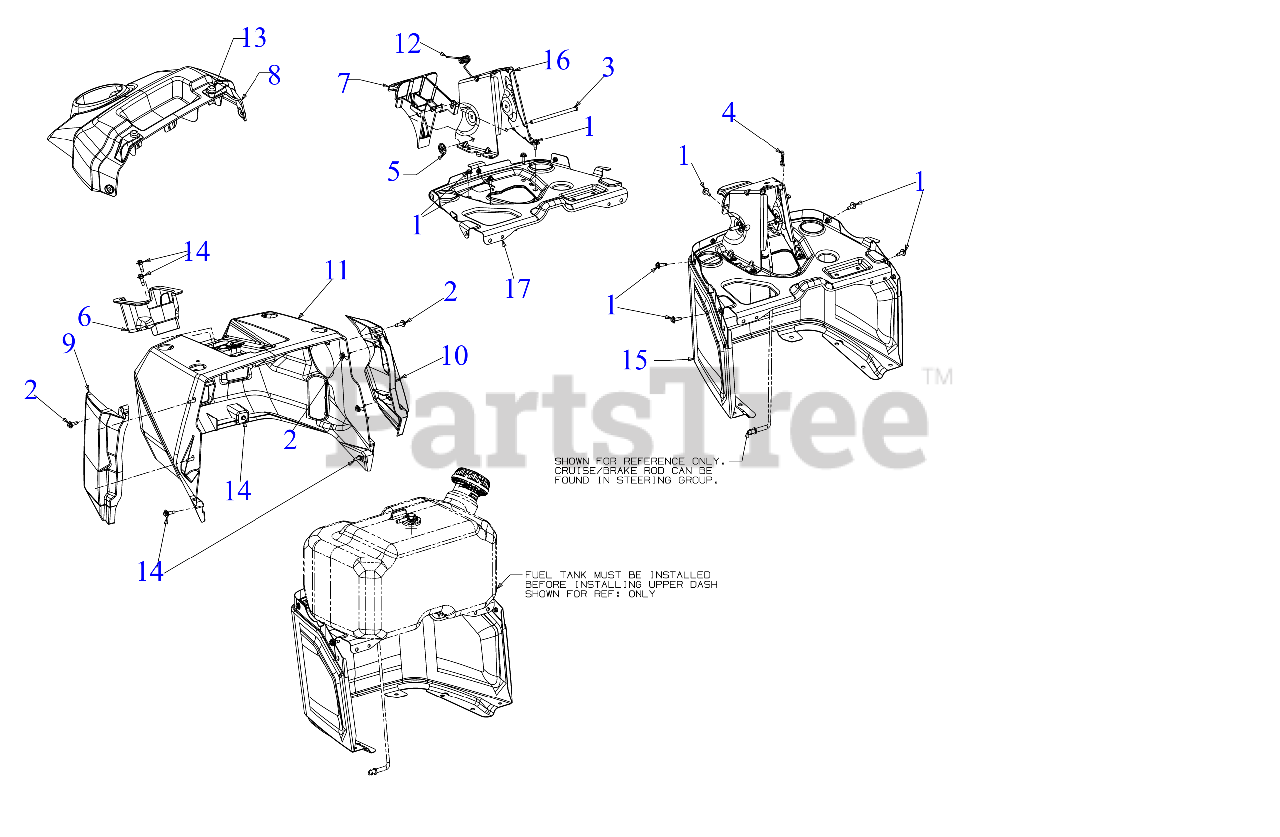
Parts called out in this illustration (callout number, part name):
1	SCREW M6-1 x .625
2	SCREW 1/4-10 x .750
3	HINGE PIN .25 x 4.50
4	BOW TIE COTTER PIN 1/4-5/16
5	PUSH NUT
6	STEERING SHAFT BEARING
7	CRUISE/BRAKE DASH LEVER
8	UPPER DASH CAP (CRAFTSMAN)
9	DASH SIDE CAP (RH)
10	DASH SIDE CAP (LH)
11	UPPER DASH
12	TORSION SPRING .330 ID
13	BUMPER, .62 DIA x .3
14	SHOULDER SCREW M6-1 .368 X.115
